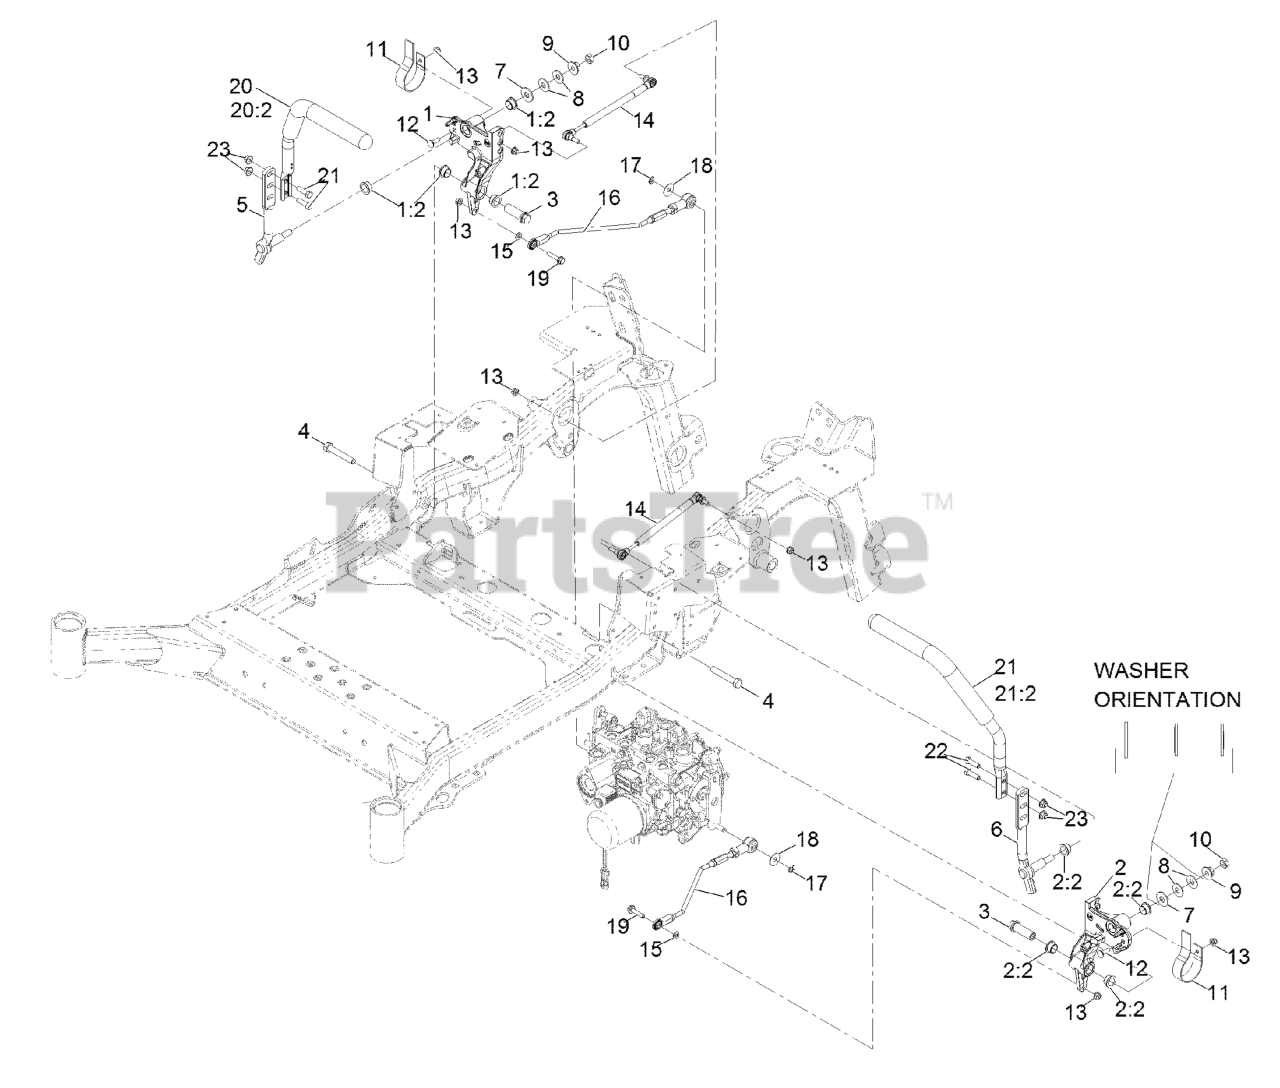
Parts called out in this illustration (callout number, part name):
1	RH MOTION CONTROL AND BUSHING ASM
1:2	BUSHING-FLANGE
2	LH MOTION CONTROL AND BUSHING ASM
2:2	BUSHING-FLANGE
3	HUB-THREADED
4	SCREW-HH
5	LEVER-CONTROL MOTION, RH
6	LEVER-CONTROL MOTION, LH
7	WASHER-FLAT
8	WASHER-SPRING
10	NUT-JAM
11	SPRING-LEAF
12	BOLT-CARR
13	NUT-HF, NI
14	DAMPER-CONTROL, MOTION
15	WASHER-PLAIN
16	FRONT LINKAGE ROD ASM
17	RING-RETAINING
18	WASHER-PLAIN
19	SCREW-HHF
20	RH STEERING HANDLE ASM
20:2	GRIP-LEVER, CONTROL
21	LH STEERING HANDLE ASM
21:2	GRIP-LEVER, CONTROL
22	SCREW-HH
23	NUT-HF, NI
